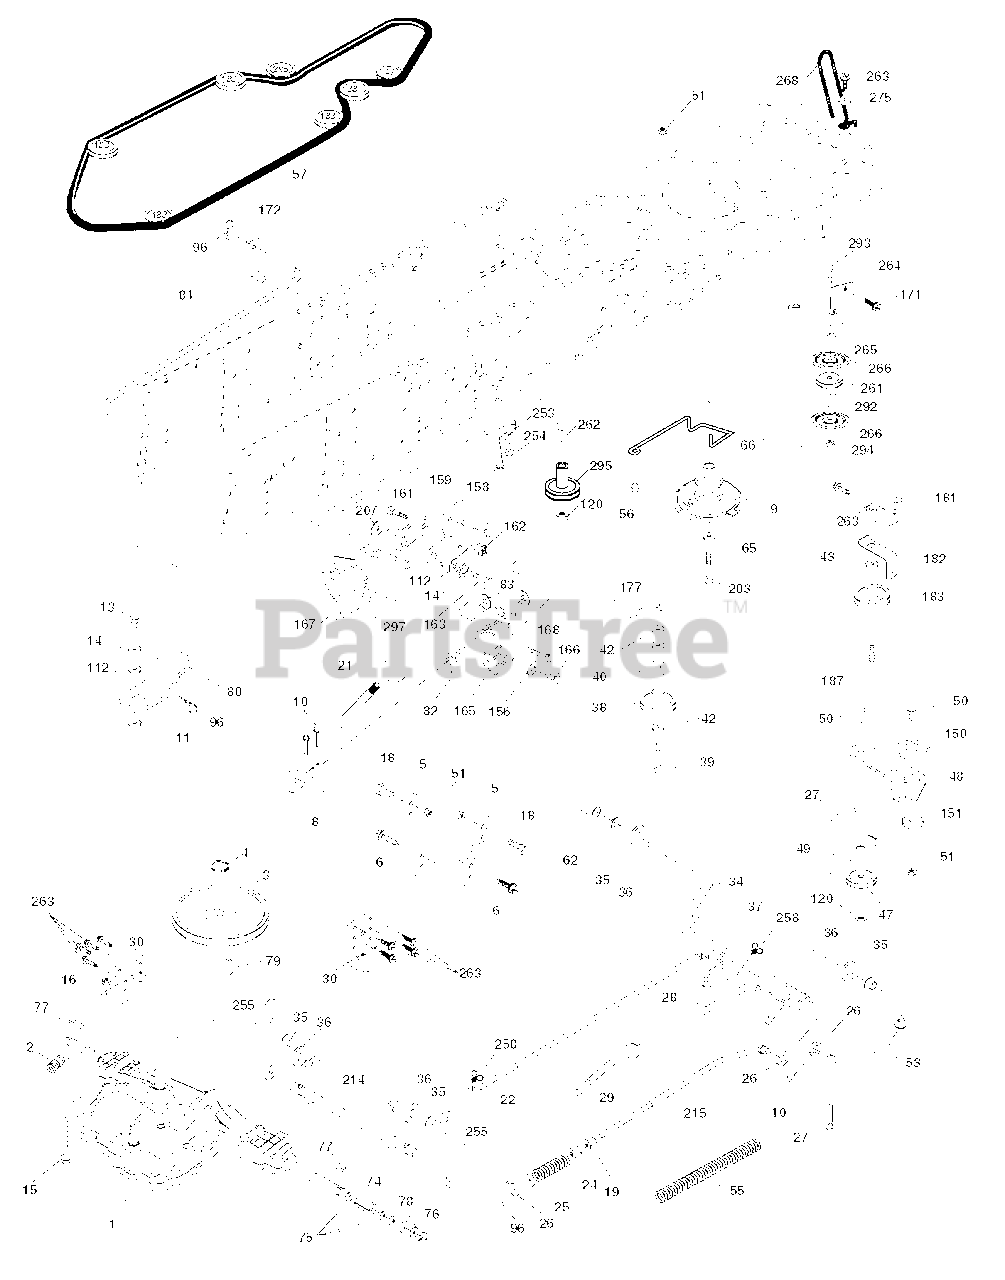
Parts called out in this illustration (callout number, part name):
2	SPRING,BRAKE RETURN
4	RETAINING RING LT
5	STRAP TORQUE
6	SCREW 5/16"
8	ROD SHIFT FENDER ADJUST LT
10	PIN COTTER
11	WASH-SHFT PLT LT
13	BOLT 1/4-28X3/4
14	LOCKWASHER
15	BOLT HEX 5/16-18 GR 5
16	NUT.71038.31-18.HEX.NYLOCK
19	NUT
21	KNOB T (1/2-HOLE)
24	NUT
25	SPRING ROD LT
27	COTTER PIN
28	ROD, PARKING BRAKE
29	PLUNGER CAP
30	BRKT, MOUNT TRNSAXLE
34	SHAFT, FOOT PEDAL
35	BEARING.NYLON
36	WASHER LT
37	DRIVE PIN
38	PULLEY.FLAT
42	WASHER
47	IDLER PULLEY
48	BELLCRANK, CLUTCH
49	RETAIN BELT
50	BOLT.3/8-16X1.50
51	LOCKNUT
53	LINK.CLUTCH.7.66.2005
55	SPRING, RETURN LT
56	SCREW.3/8-16
57	V-BELT.KEV.111"
62	PEDAL COVER T
65	LOCKWASHER
66	KEEPER BELT ENGINE
74	SPACER AXLE
76	E-RING LT
77	SQUARE KEY
80	ARM SHIFT
82	SHIFT SPRING
83	WASHER
96	RETAINER M
112	WASHER LT
120	NUT LOCK FLG 3/8-16 UNC
150	BUSHING.BELLCRANK.GRD.DR
151	WASHER 12/32X2X10GA
156	WASHER.SRRTD.5/16
158	BRACKET
159	HUB.SHIFT
161	BOLT
162	NUT.CROWNLOCK.1/4
165	RP BRACKET
167	BRACKET
168	BOLT.SHOULDER.5/16-18X
183	PULLEY.V-IDLER.
187	BOLT.5/16-18X1.25
207	WASHER NYL
254	SCREW 3/8-16X1
258	CLIP RETAINER
261	FLAT IDLER PULLEY
263	SCREW, 3/8-16X3/4
264	DECAL.HOOD.ELITE.(PAIR)MCCULLO
275	WASHER
294	NUT, HEX 3/8-16
295	PULLEY IDLER COMPOSITE
297	SCREW LT.3/8-46X5/8
